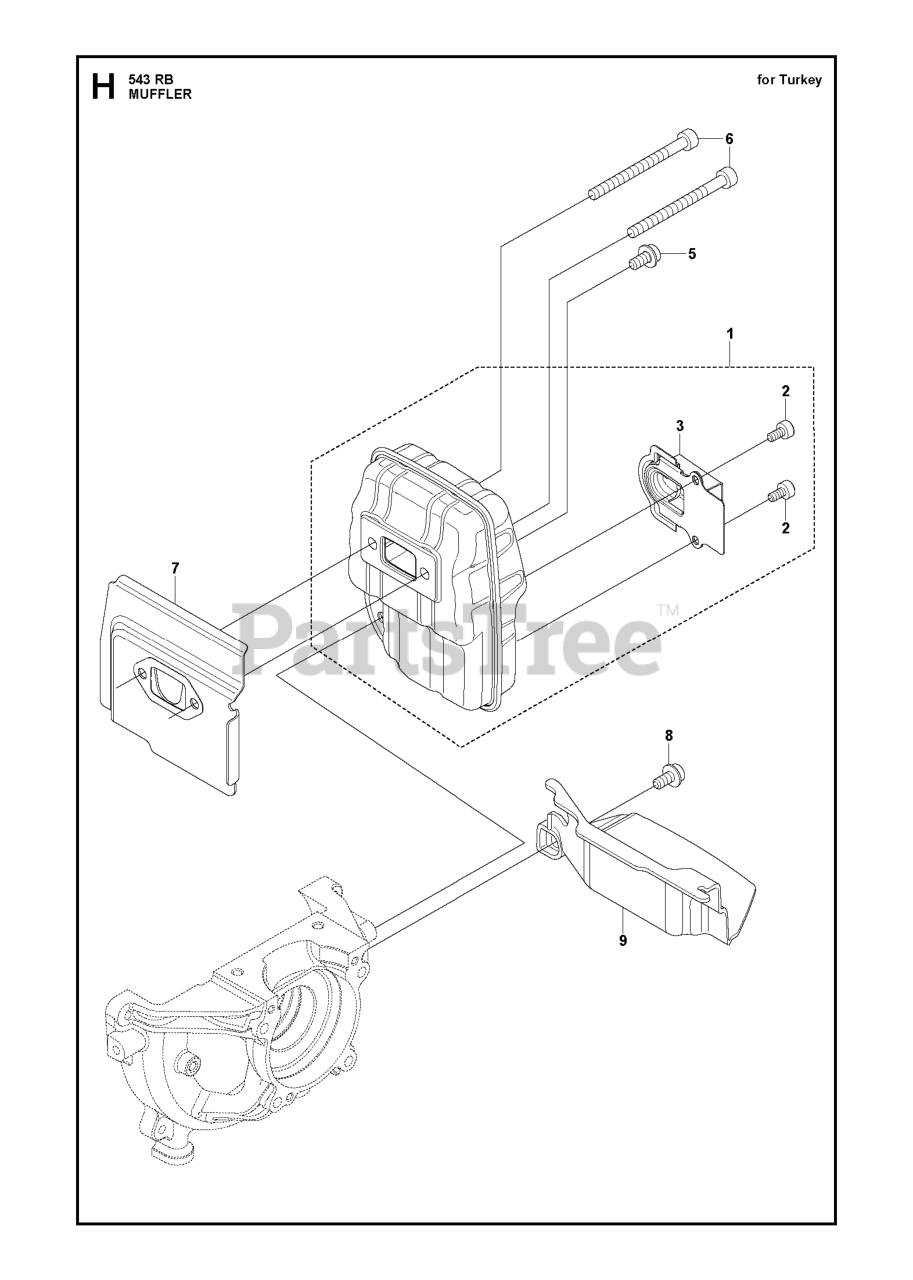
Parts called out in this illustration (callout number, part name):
1	MUFFLER ASSY
2	BOLT
3	GUIDE
5	BOLT (RPLS T495051010-11)
6	BOLT
7	GASKET
8	BOLT (RPLS T495051010-11)
